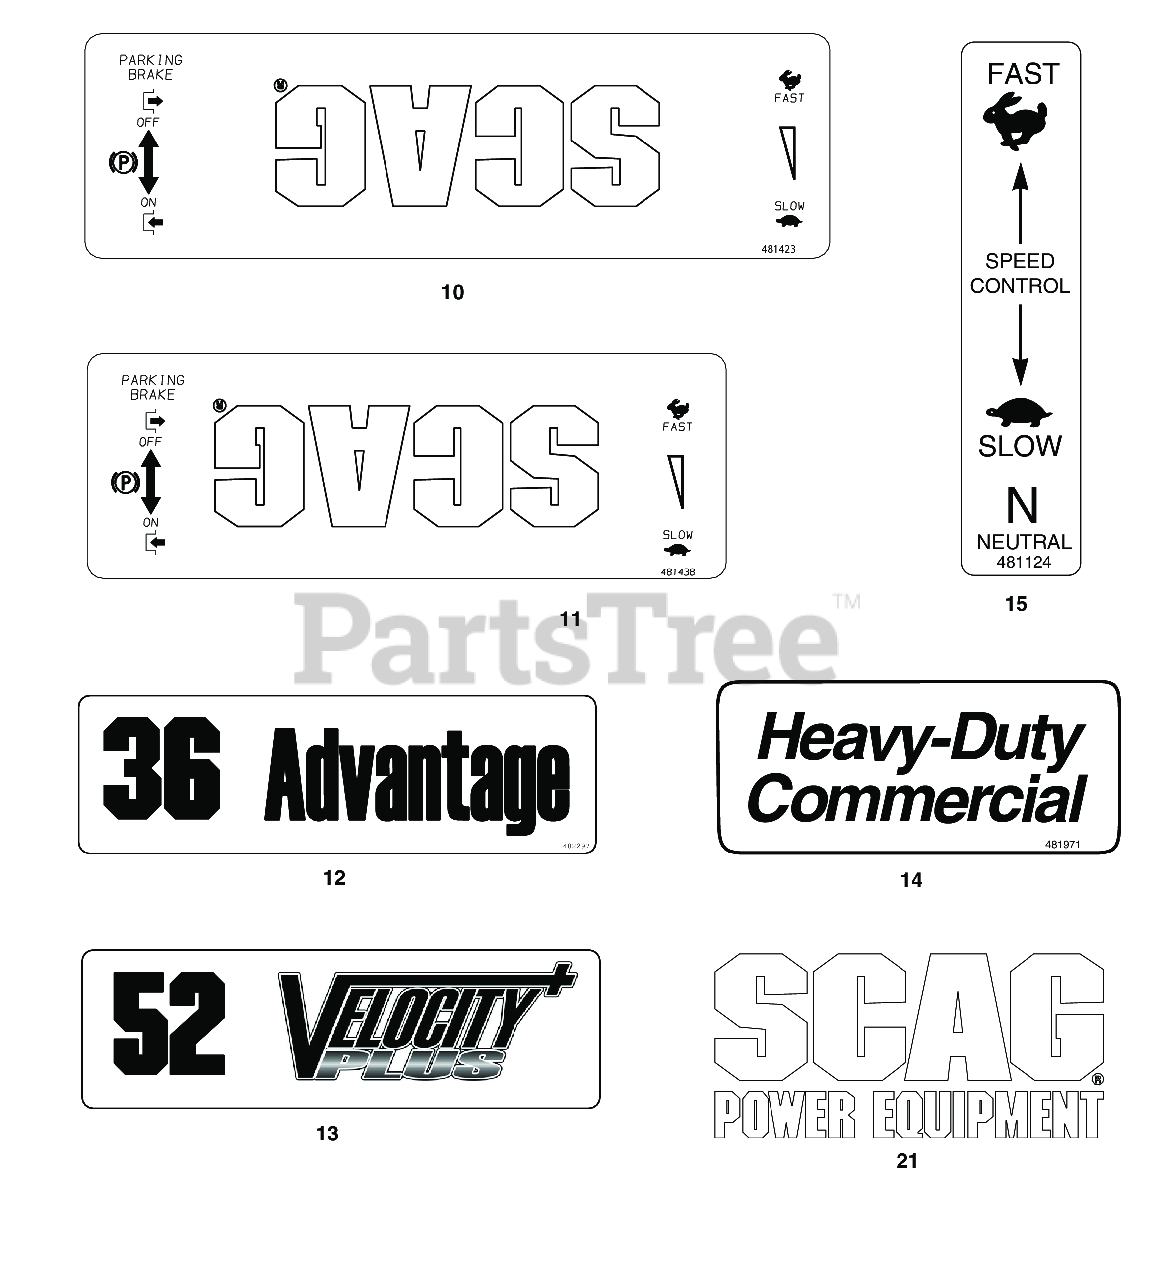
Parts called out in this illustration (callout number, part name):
10	Decal, Instrument Panel - Front (SWZ-19KAI & SWZ-21KAE only)
11	Decal, Instrument Panel - Front
12	DECAL, ADVANTAGE - 36
13	DECAL, VELOCITY PLUS - 48
14	Decal, Heavy Duty Commercial
15	Decal, Speed Control
21	Decal, Scag Power Equipment (Fuel Tank)
23	Decal 52V 483201 Decal 61V
23	DECAL, VELOCITY PLUS - 61
